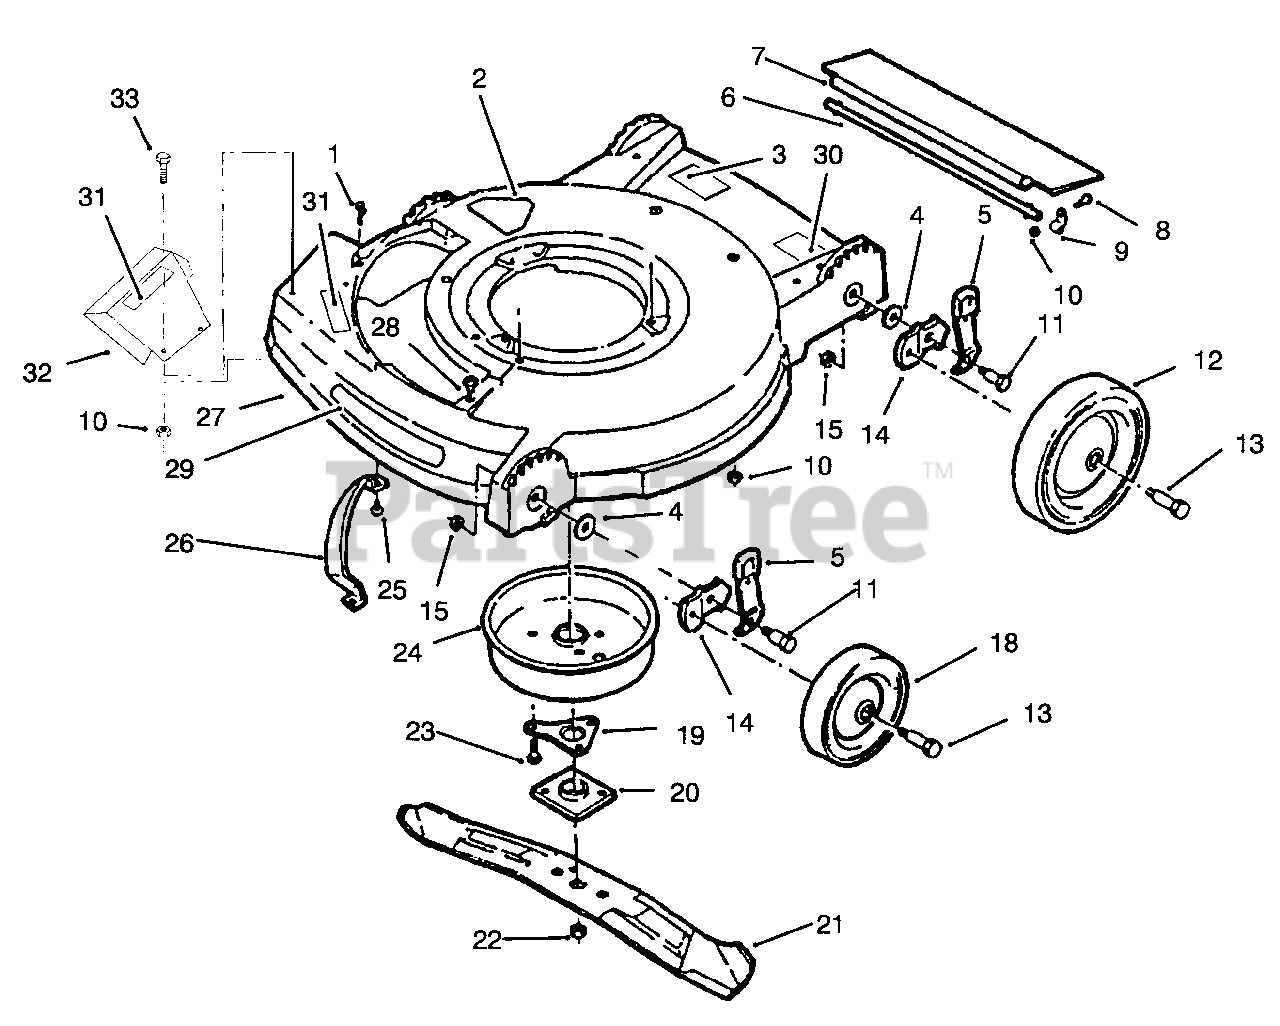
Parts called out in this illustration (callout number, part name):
1	Screw-Sems, Plate Cover
2	Decal-DIN
3	Decal-Danger
5	Knob & Spring-Adj.
6	Rod-Shield, Trailing
7	Shield-Trailing
9	Clamp-Rod, Shield
10	Nut-Lock
11	Bolt-Shoulder
12	Wheel-Rear, 8"
13	Bolt-Wheel
14	Bracket-Wheel Adj.
15	Nut-Lock
18	Wheel-Front,6"
19	Plate-Support, Crankshaft
20	Collar & Plate
21	Blade-21"
22	Nut-Blade
23	Screw-Plate to Muffler Cover
24	Cover-Muffler
25	Screw-Toe Bar to Housing
26	Toe Bar
27	Assembly-Housing (Incl. Ref.#2, 3, & 31)
28	Grommet
29	Decal-Deck 550C
30	Decal-Noise
31	Decal-Warning
32	Guard-Plate
33	Screw-Hex Hd.
